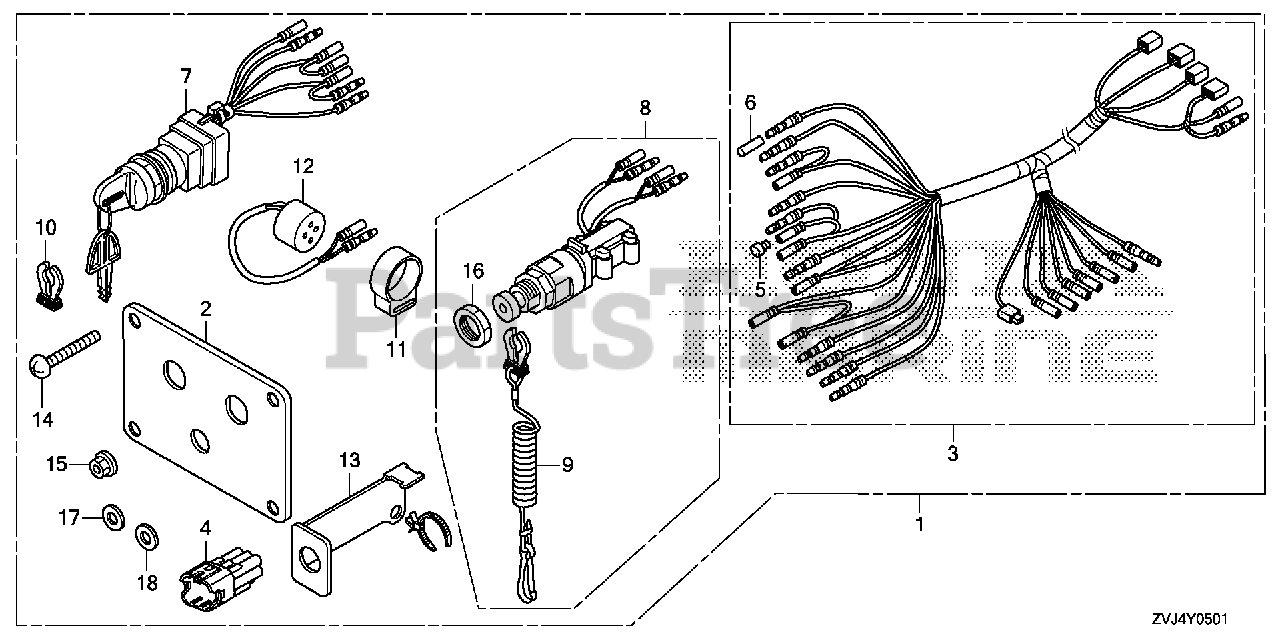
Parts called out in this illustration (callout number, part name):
1	PANEL KIT, SWITCH (TWIN)
2	PANEL, CONTROL (TWIN)
3	HARNESS ASSY., SWITCH PANEL
4	DUMMY, WATERPROOF CONNECTOR (GREEN)
5	PLUG, CONNECTOR (INNER)
6	PLUG, CONNECTOR (OUTER)
7	SWITCH ASSY., COMBINATION
8	SWITCH ASSY., EMERGENCY STOP (TWIN)
9	WIRE, EMERGENCY
10	CLIP, EMERGENCY LOCK
11	SUSPENSION, AUDIBLE PILOT
12	BUZZER, WARNING
13	BRACKET
14	SCREW, PAN (5X40)
15	NUT, FLANGE (5MM)
16	NUT
17	WASHER, PLAIN (5MM)
18	WASHER, SPRING (5MM)
